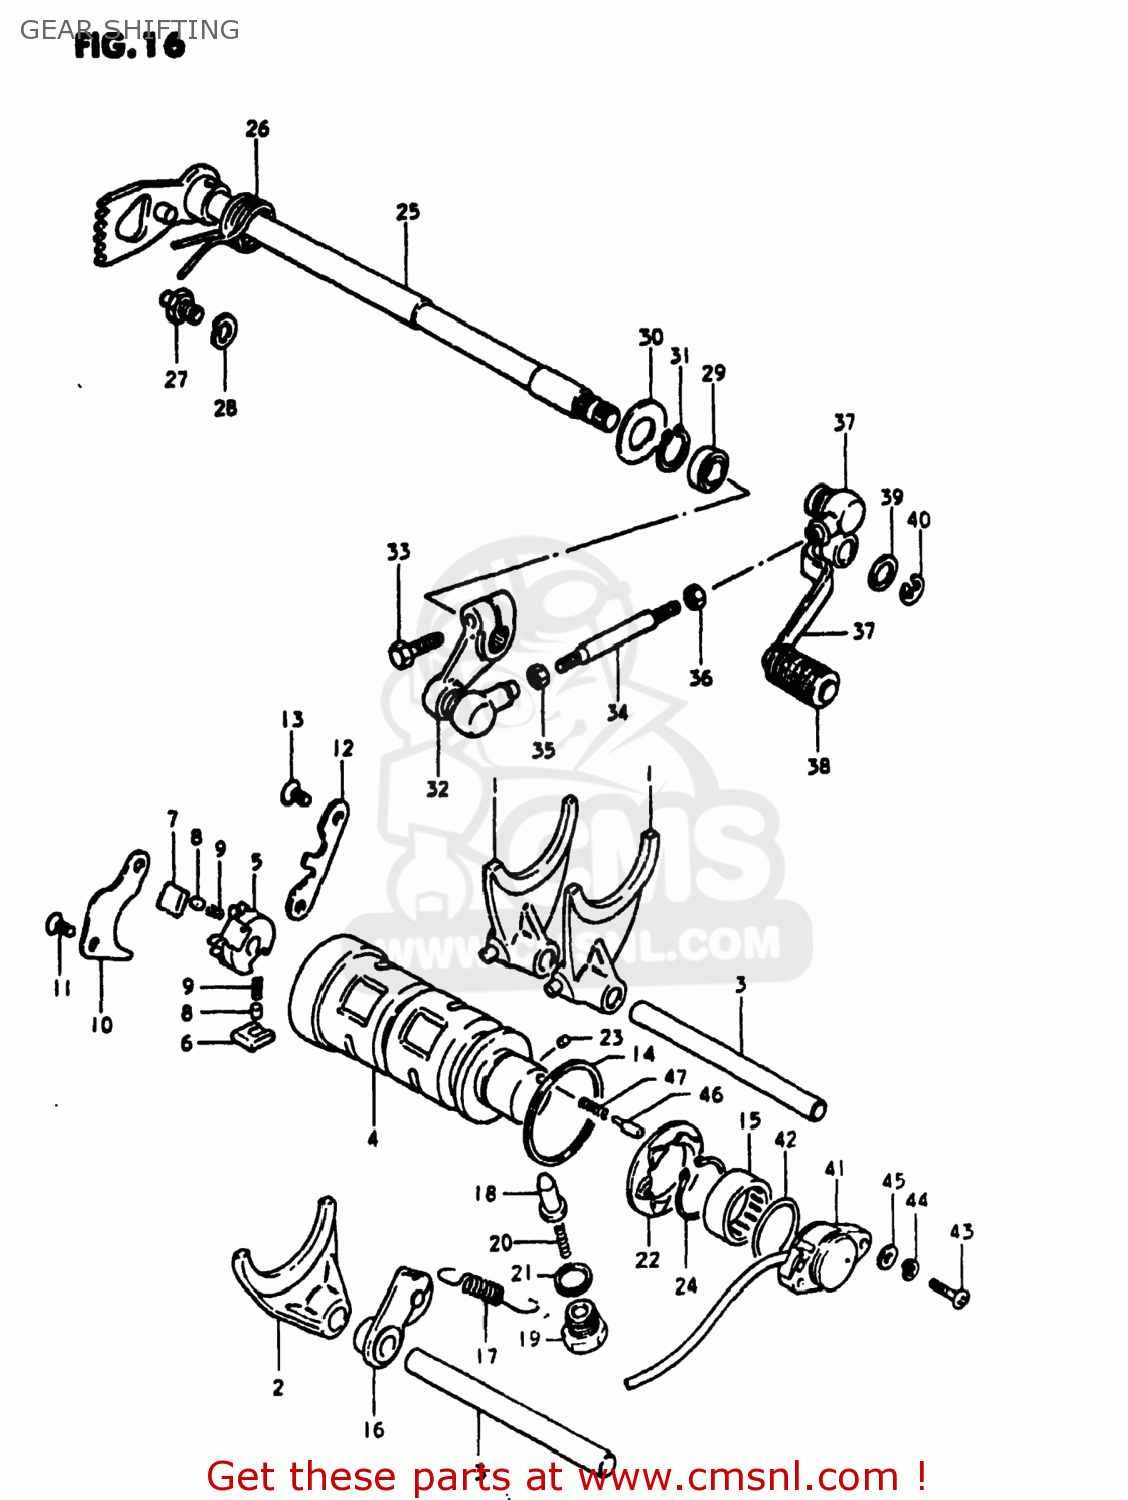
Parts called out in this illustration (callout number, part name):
1	FORK,GEAR SHIFT NO.1
2	FORK,GEAR SHIFT NO.3
3	SHAFT,GEAR SHIFT FORK
4	CAM,GEAR SHIFT
5	RETAINER,GEAR SHIFT CAM
6	PAWL,GEAR SHIFT NO.1
7	PAWL,GEAR SHIFT NO.2
8	PIN(5X8)
9	SPRING
10	LIFTER,GEAR SHIFT PAWL
11	SCREW
12	GUIDE,GEAR SHIFT CAM
13	SCREW
14	WASHER(40X45X1)
15	BEARING(25X32X12)
16	STOPPER,GEAR SHIFT CAM
17	SPRING
18	STOPPER,GEAR SHIFT CAM NO.2
19	HOLDER,GEAR SHIFT CAM STOP SPR
20	SPRING
21	GASKET(14X19.2X2) (NAS)
22	PLATE,GEAR SHIFT CAM STOPPER
23	PIN 4X6
24	CIRCLIP
25	SHAFT,GEAR SHIFT
26	SPRING
27	STOPPER,GEAR SHIFT CAM
28	WASHER
29	OIL SEAL
30	WASHER (12.5X27X1.6)
31	SPRING,RETAINER
32	ARM,GEAR SHIFT LINK
33	BOLT
34	ROD,GEAR SHIFT LINK
35	NUT
36	NUT
37	LEVER ASSEMBLY,GEAR SHIFTING
38	RUBBER,GEAR SHIFT PEDAL
39	WASHER(12.5X20X1)
40	CIRCLIP
41	TERMINAL BASE,NEUTRAL SWITCH
42	O-RING (D:2.4 ID:26.2)
43	SCREW 5X20
44	LOCK WASHER
45	WASHER
46	PIN(5X15.5)
47	SPRING
